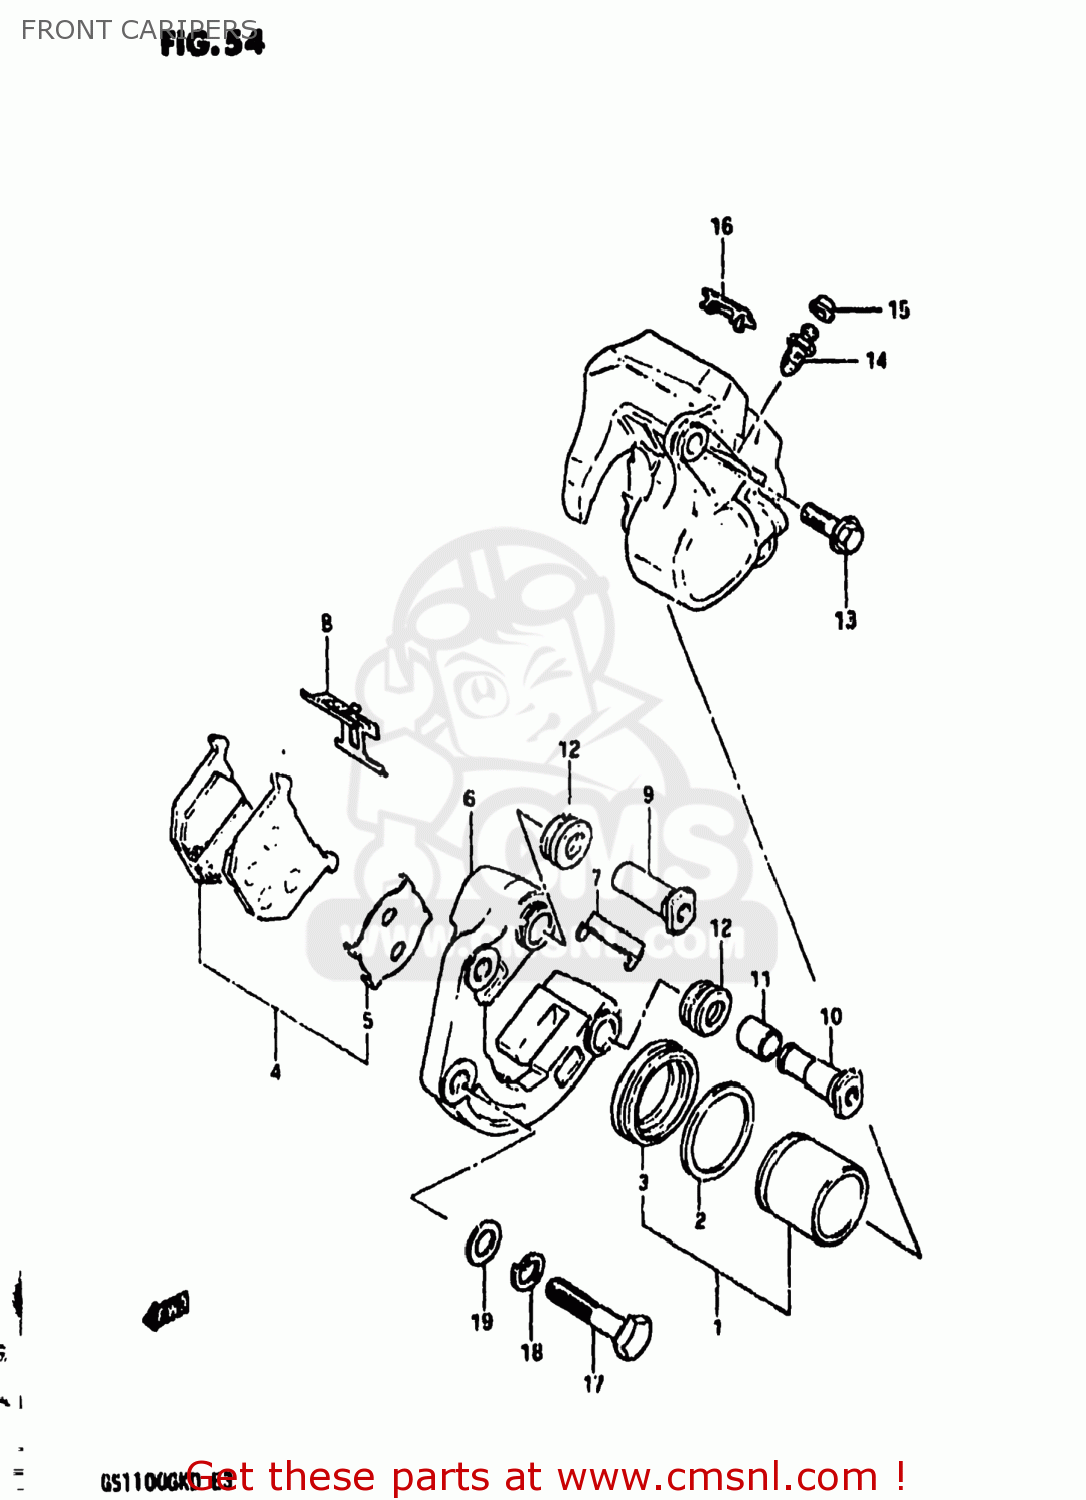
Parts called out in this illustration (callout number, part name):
0	CALIPER ASSEMBLY,FRONT,LEFT
1	PISTON SET
2	SEAL,FR CALIPE
3	BOOT,PISTON
4	PAD SET,BRAKE (MCA)
5	SHIM,PAD
6	CARRIER,CALIPER,LEFT
7	GUIDE,PAD
8	SPRING,PAD
9	AXLE NO.1
10	AXLE NO.2
11	BUSH,AXLE
12	BOOT,AXLE
13	BOLT
14	BLEEDER
15	CAP,BREATHER
16	COVER
17	BOLT 10X53.5
18	LOCK WASHER
19	WASHER
